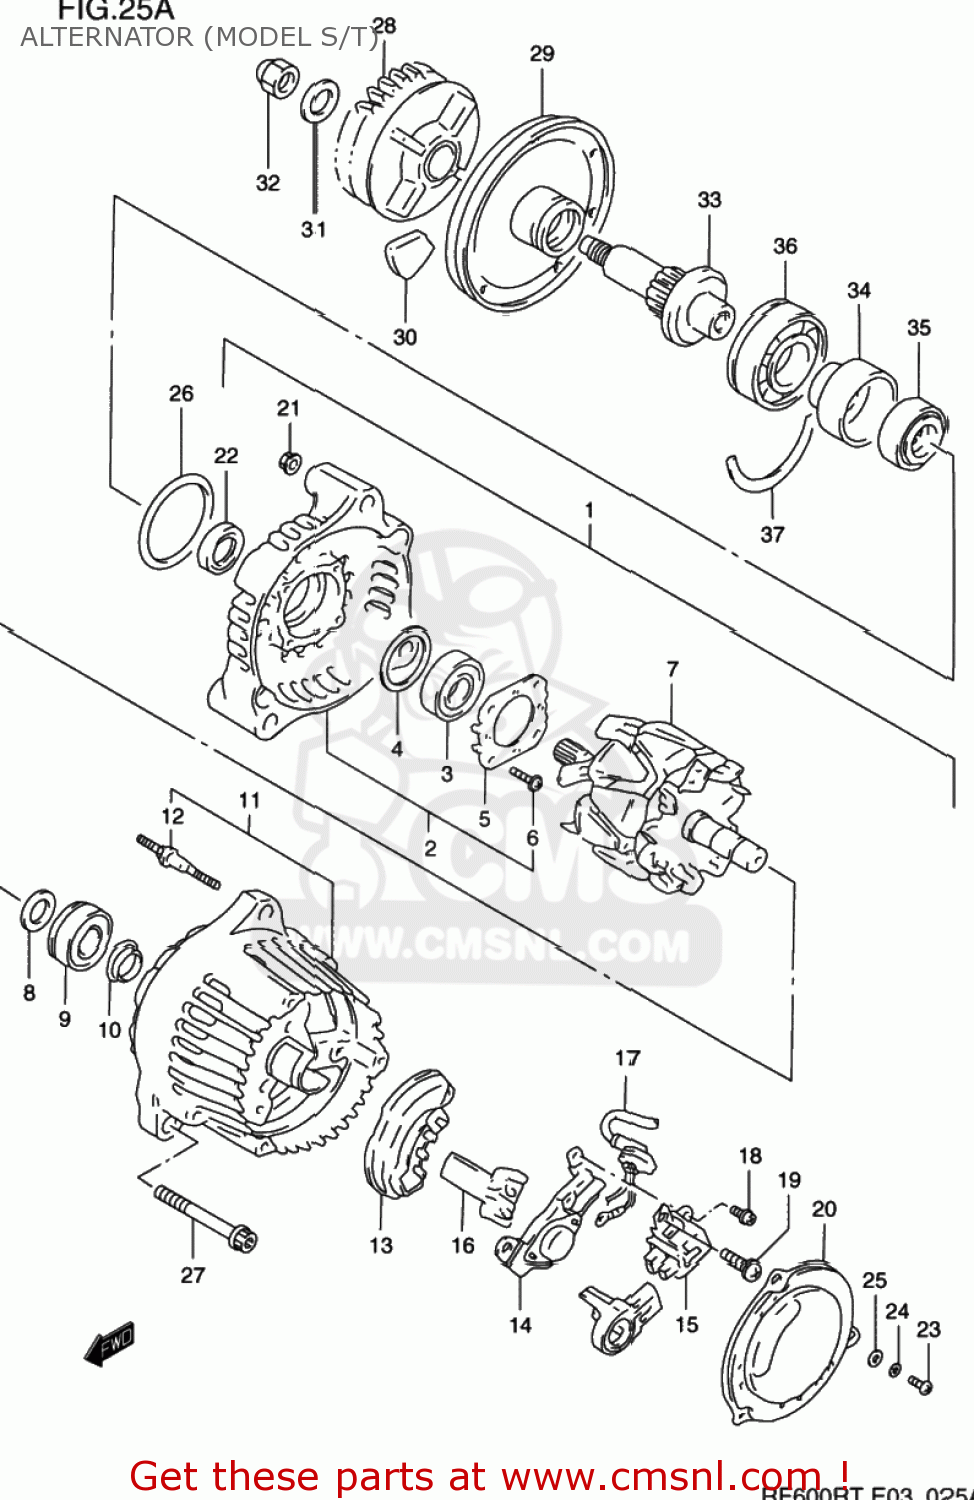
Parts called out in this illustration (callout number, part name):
1	ALTERNATOR ASSY
2	FRAME,DRIVE END
3	BEARING
4	COVER,BEARING
5	RETAINER,BEARING
6	SCREW,BEARING RETAINER
7	ROTOR ASSEMBLY
8	COVER,BEARING
9	BEARING
10	COVER(2)
11	FRAME,END
12	STUD BOLT
13	HOLDER,RECTIFIER
14	REGULATOR
15	HOLDER,BRUSH
16	COVER,RECTIFIER
17	WIRE,LEAD
18	SCREW 4X6
19	SCREW
20	COVER
21	NUT
22	SERVICE KIT(A)
23	SCREW
24	LOCK,WASHER
25	WASHER
26	O RING
27	BOLT
28	GEAR,GENERATOR DRIVEN
29	HOUSING,GENERATOR DAMPER
30	DAMPER,GENERATOR
31	WASHER
32	NUT
33	SHAFT,GENERATOR DRIVE
34	HUB,GENERATOR DRIVE
35	COUPLING COMP,GENERATOR
36	BEARING(25X52X13)
37	C RING
